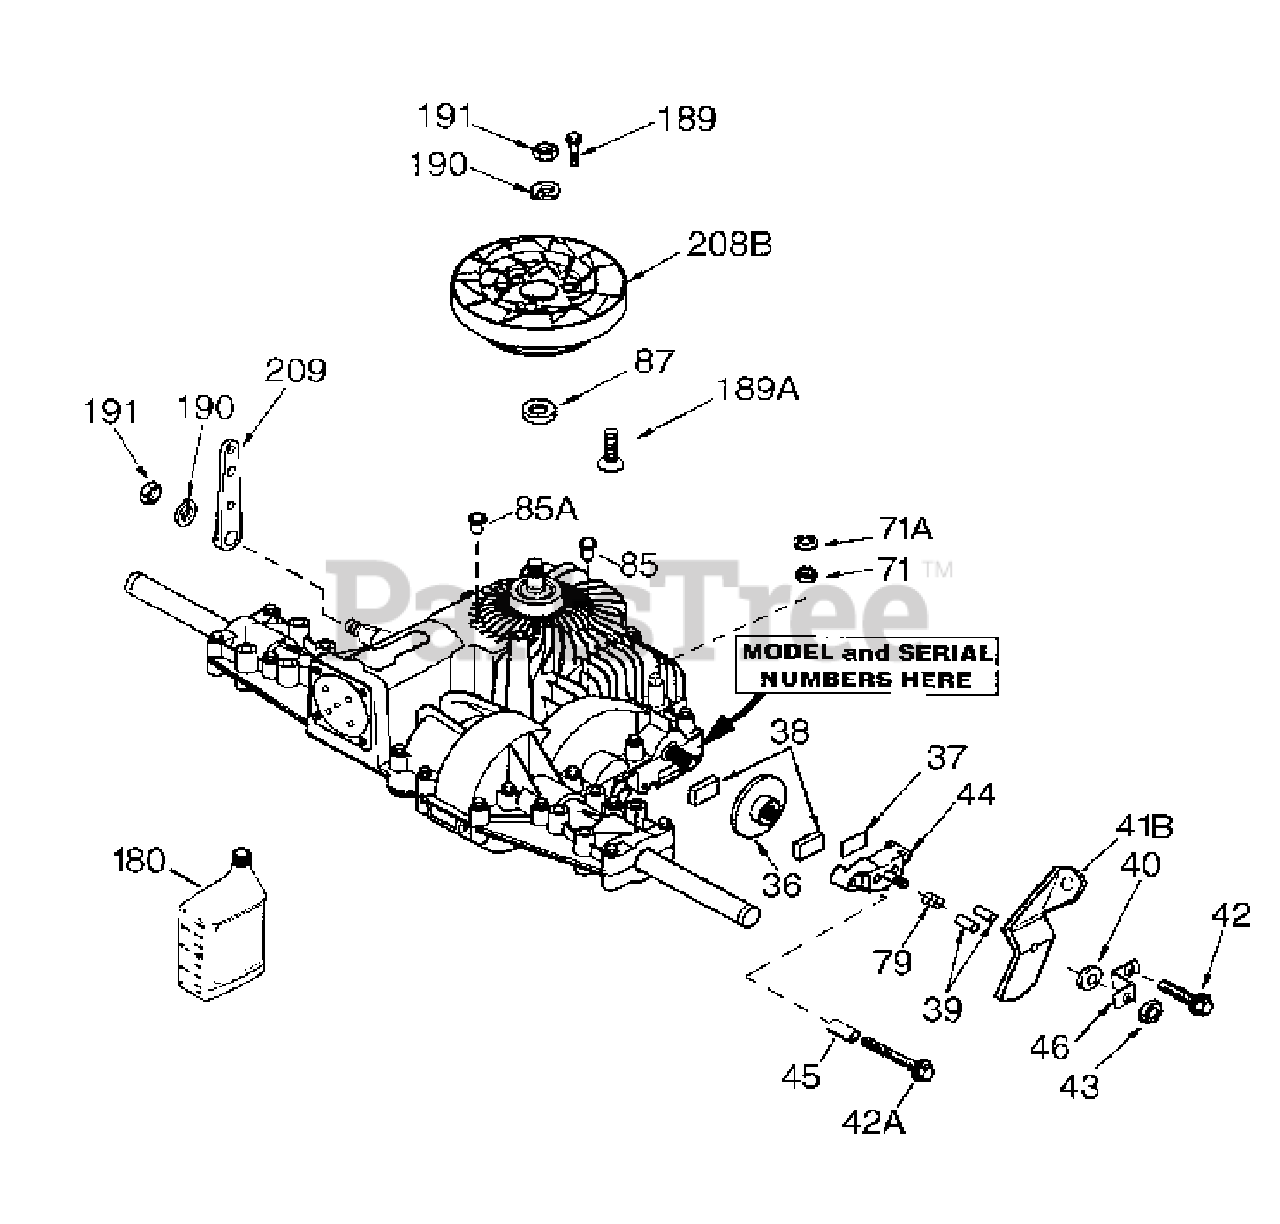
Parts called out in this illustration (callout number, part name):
36	Brake Disc
37	Brake Pad Plate
38	Brake Pad (pkg of 2)
39	Dowel Pin
40	Flat Washer
41B	Brake Lever
42	Screw, 1/4-20 x 1-1/4"
42A	Screw, 1/4-20 x 2-1/4"
43	Locknut, 5/16-24
44	Brake Pad Holder
46	Brake Lever Bracket
71	Square Cut Ring
71A	Pushnut, 9/16"
85	Oil Fill Plug
85A	Tube Plug, 3/8"
87	Oil Seal, 5/8"
180	Gear Oil 80W90
189	Drive Screw #6 x 1/2"
189A	Screw, 10-32 x 1/2"
190	Lockwasher
191	Nut, 7/16-20
208B	Fan/Coupling
209	Control Lever
